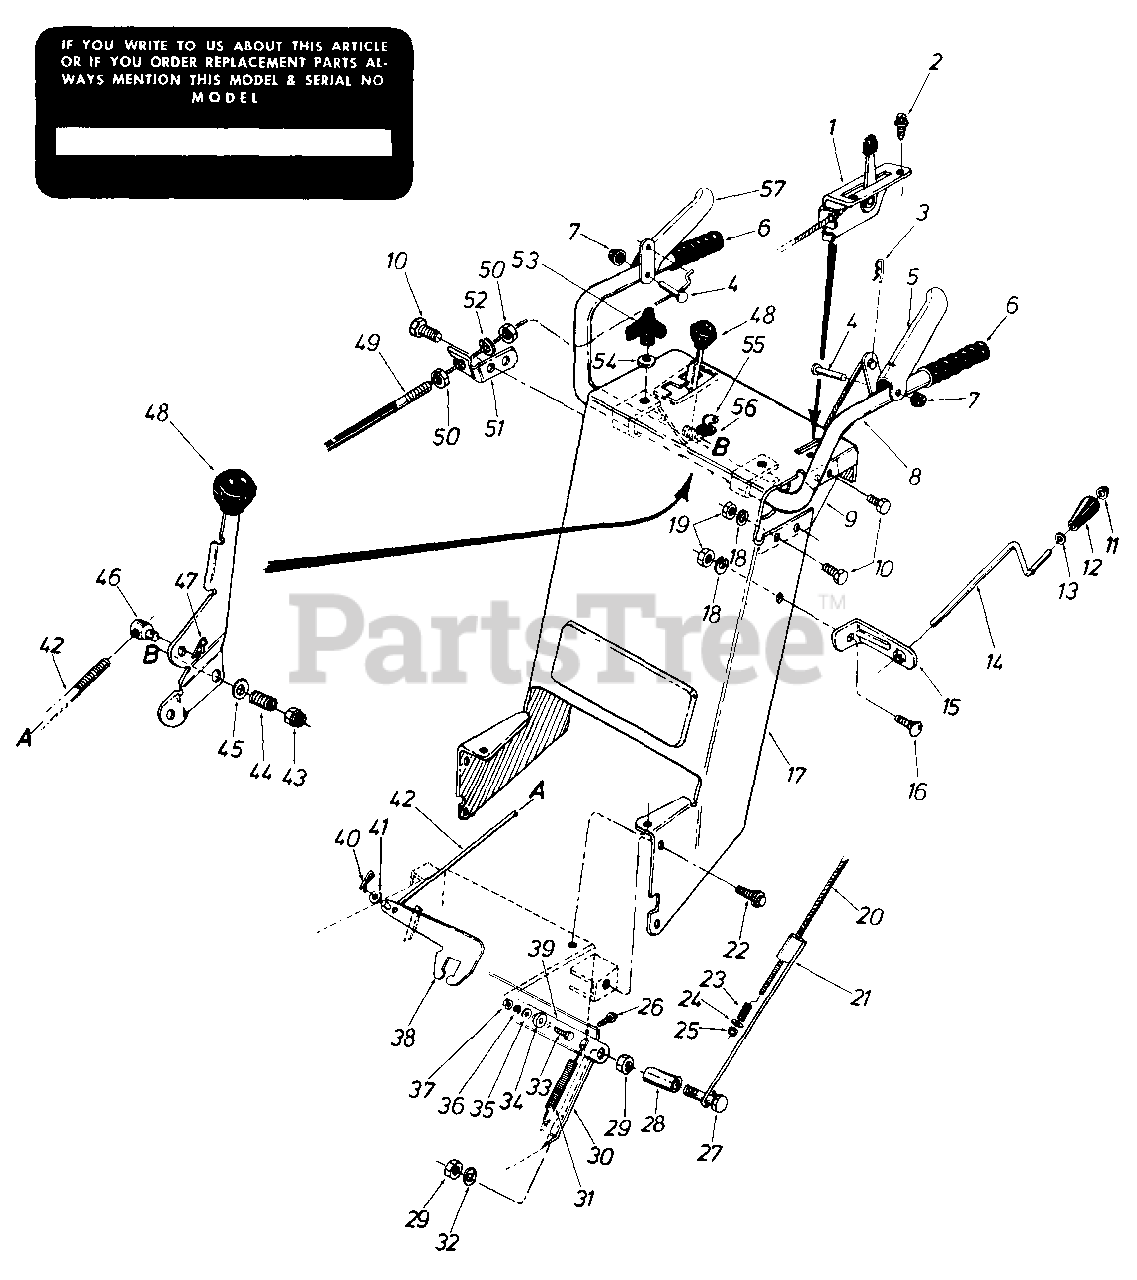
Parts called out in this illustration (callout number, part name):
1	Throttle Control Ass'y. - Comp.
2	Hex Wash. Self-Tap Scr. #8 x .50" Lg.
3	Cotterpin 3/32" Dia. x 1.00" Lg.
4	Clevis Pin .375" Dia. x 1.88" Lg.
5	Auger Clutch Grip Ass'y. - L.H.
6	Grip Handle
7	Push Cap .375" Rod - Black
8	Handle Ass'y.
9	Handle Support Brkt.
10	Hex Bolt 5/16-24 x .62" Lg.
11	Push Nut 3/8" Rod
12	Black Knob - 3/8" Dia. Hole
13	Fl-Wash. .385" I.D. x .62" O.D. x .063"
14	Chute Crank .38" Dia. x 35 Lg.
15	Chute Control Brkt.
16	Carriage Bolt 5/16-18 x .62" Lg.
17	Handle Panel Ass'y.
18	L-Wash. 5/16" I.D.
19	Hex Nut 5/16-24 Thread
20	Lockout Cable - 30.5" Lg.
21	Auger Clutch Rod Ass'y.
22	Hex Wash. Self-Tap Scr. 5/16-24 x .50" Lg.
23	Compression Spring
24	Fl-Wash. .28" I.D. x .74" O.D. x .063"
25	Hex Ins. L-Nut 3/18-16 Thread
26	Hex Wash. Self-Tap Scr. 5/16-24 x .50" Lg.
27	Hex Bolt 1/4-28 x 2.5" Lg.
28	Spacer .38" I.D. x .50" O.D. x 1.44" Lg.
29	Hex Nut 1/4-28 Thd.
30	Frame Cover
31	Ext. Spring .38" O.D. x 3.25" Lg.
32	L-Wash. 1/4" I.D.
33	Hex Sems Scr. 5/16-18 x .75" Lg.
34	Shoulder Spacer
35	Fl-Wash. .344" I.D. x 1.125" O.D. x .125"
36	L-Wash. 5/16" I.D.
37	Hex Cent. L-Nut 5/16-18 Thd.
38	Shifting Brkt.
39	Thrower Clutch Brkt.
40	Cotterpin 3/32" Dia. x 1.0" Lg.
41	Fl-Wash. .344" I.D. x .62" O.D. x .063"
42	Shifting Rod
43	Hex Ins. L-Nut 3/8-24 Thd.
44	Compression Spring .39" I.D. x .88" Lg.
45	Bell-Wash. .40" I.D. x .88" O.D. x .06"
46	Ferrule - Engagement
47	Cotterpin 3/32" Dia. x 1.0" Lg.
48	Shift Handle Ass'y.
49	Drive Clutch Control Cable
50	Hex Jam Nut 5/16-24 Thd.
51	Cable Support Brkt.
52	L-Wash. 5/16" I.D.
53	Three Arm Knob 5/16-18 Thd.
54	Bell-Wash. .345" I.D. x .62" O.D. x .063"
55	Ignition Key
56	Ignition Switch
57	Drive Clutch Grip - R.H.
